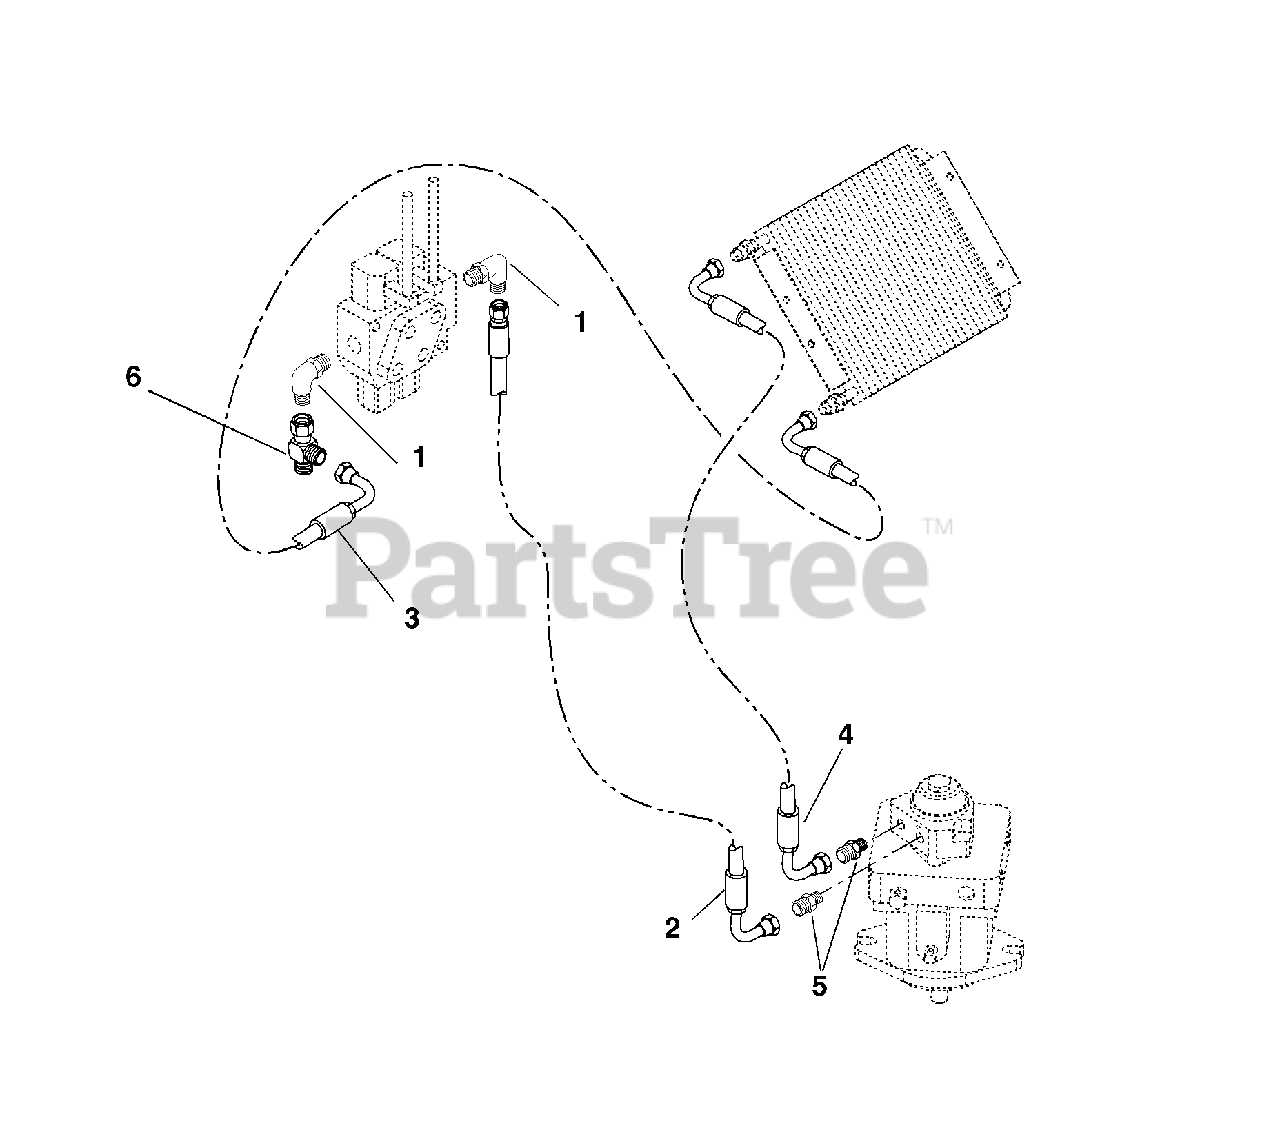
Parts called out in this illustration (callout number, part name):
1	Fitting, Hydraulic Elbow
2	Hose, Hydraulic
3	Hose, Hydraulic
4	Hose, Hydraulic
5	Fitting, Hydraulic
6	Fitting, Hydraulic
